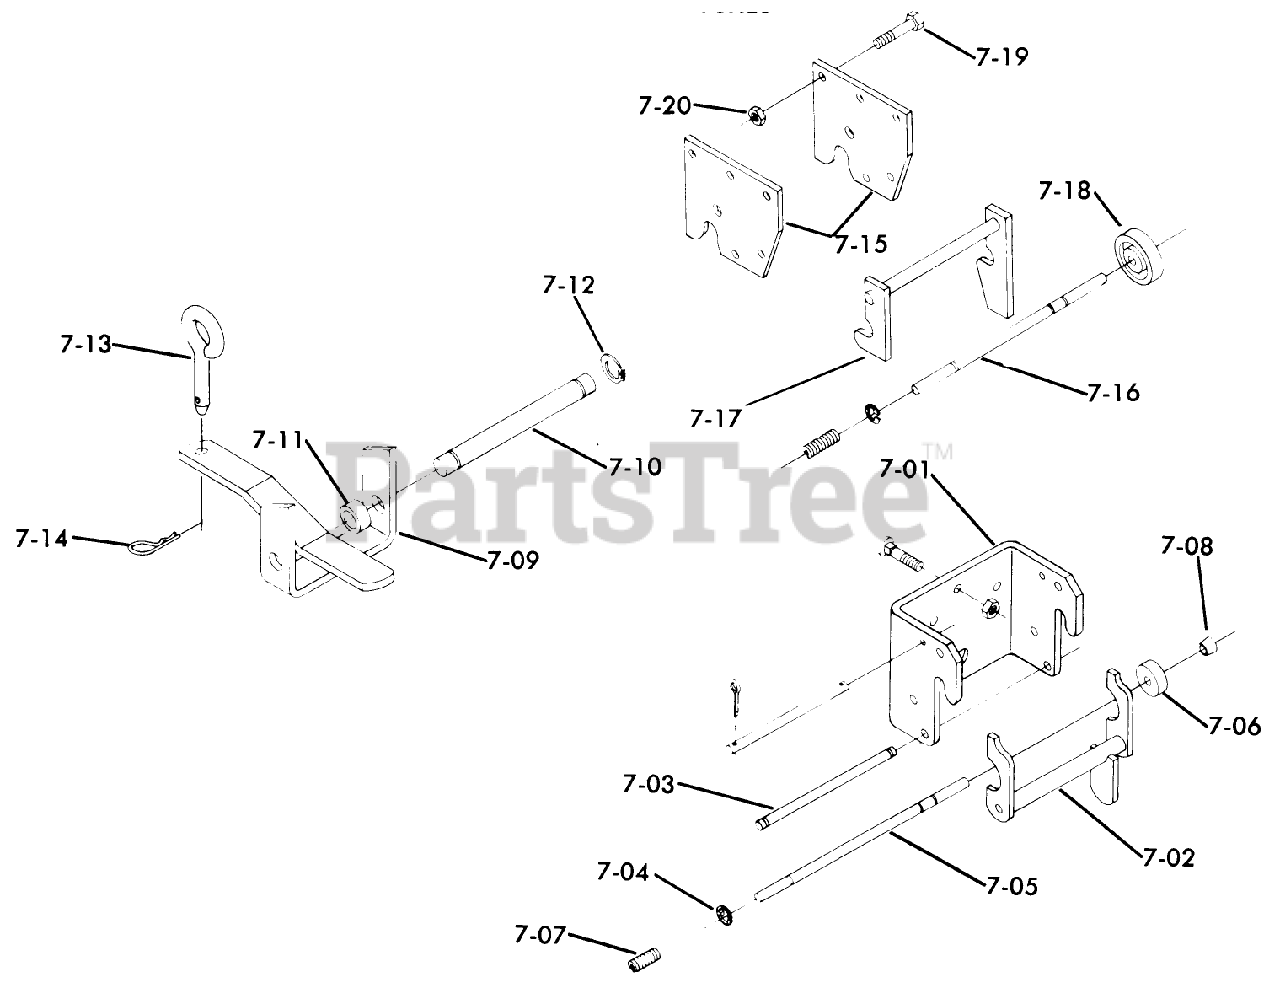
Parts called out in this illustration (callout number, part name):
7-03	ROD-LATCH PIVOT
7-04	Lock Rod
7-05	ROD-LOCK
7-07	SPRING
7-08	CAP-ROD, PLUNGER
7-10	PIN-STATIONARY HITCH
7-12	E-RING
7-14	Hairpin Cotter
